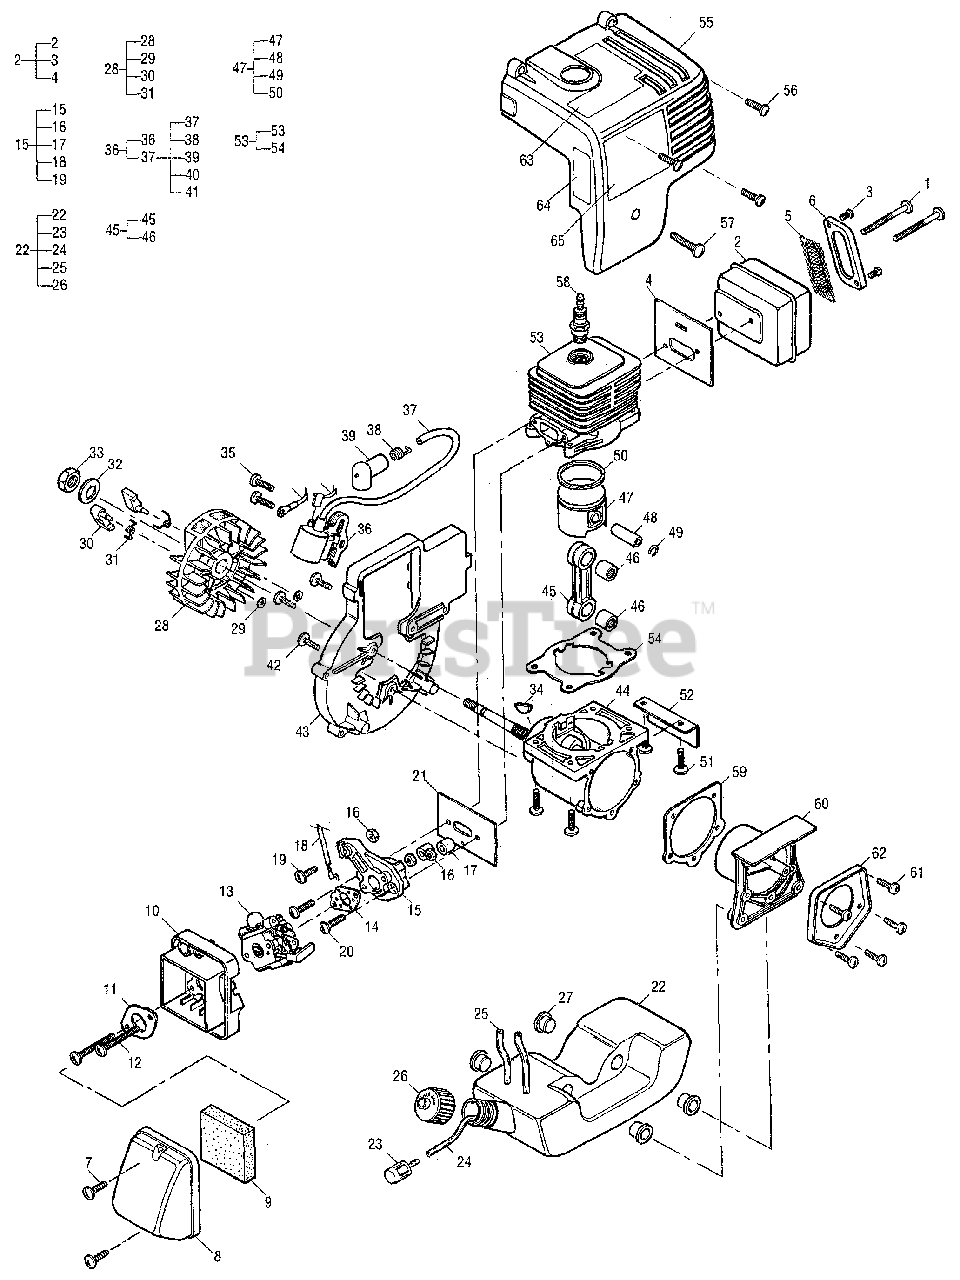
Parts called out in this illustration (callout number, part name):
1	Screw, 10-24x2.25 Taptite
2	Kit, Muffler
3	Screw
4	Plate, Muffler
5	Screen, Spark Arrester
6	Cover, Spark Arrester
7	Screw, 8-16 x .75 Tr Hd Plastite
8	Cover, Air Box
9	Filter, Air
10	Box, Air Filter
11	Plate, Air Box
12	Screw, 10-24 x 2 Torx
13	Carburetor Assembly
14	Gasket, Carburetor
15	Manifold, Carburetor
16	Nut, 10-24
17	Spacer, Rubber
18	Cable, Throttle
19	Screw, 10-24 x .62 Tr Hd Torx
20	Screw, 10-24 x .875 Taptite
21	Gasket, Manifold
22	Fuel Tank Asy
23	Filter, Fuel
24	Hose, Fuel
25	Hose, Fuel Return
26	Kit, Fuel Cap w/Retainer
27	Isolator, Fuel Tank
28	Flywheel Asy
29	Pawl Kit
29	Retainer Ring
30	Pawl, Starter
31	Spring, Starter Pawl
32	Washer, Conical Spring
33	Nut, Hex
34	Key, Flywheel
35	Screw, 10-24 x .875 Taptite
36	Ignition Asy
37	Kit, Spark Plug Wire
38	Connector, Spark
39	Boot, Spark Plug
42	Screw, 10-24 x .63
43	Shroud, Engine
44	Short Block Asy
45	Connecting Rod Asy
48	Piston Pin, C'shaft (10mm dia)
49	Ring, Retaining
50	Ring, Piston
51	Screw, 10-24 x .688 Tri Rnd
52	Shield, Muffler
54	Gasket, Cylinder
55	Cover, Cylinder/Muffler
56	Screw, 8-16 x .75 Tr Hd Plastite
57	Screw, 10-14 x .75 Torx
58	Spark Plug, RDJ8J
59	Gasket, C'case
60	Plug, C'case
61	Screw, 10-24 x .688 Tri Rnd
62	Plate, C'case
63	Starting Instr, Eng/Fr
63	Starting Instr, Eng/Sp
64	Choke Label
65	Decal, Warning, Tri
